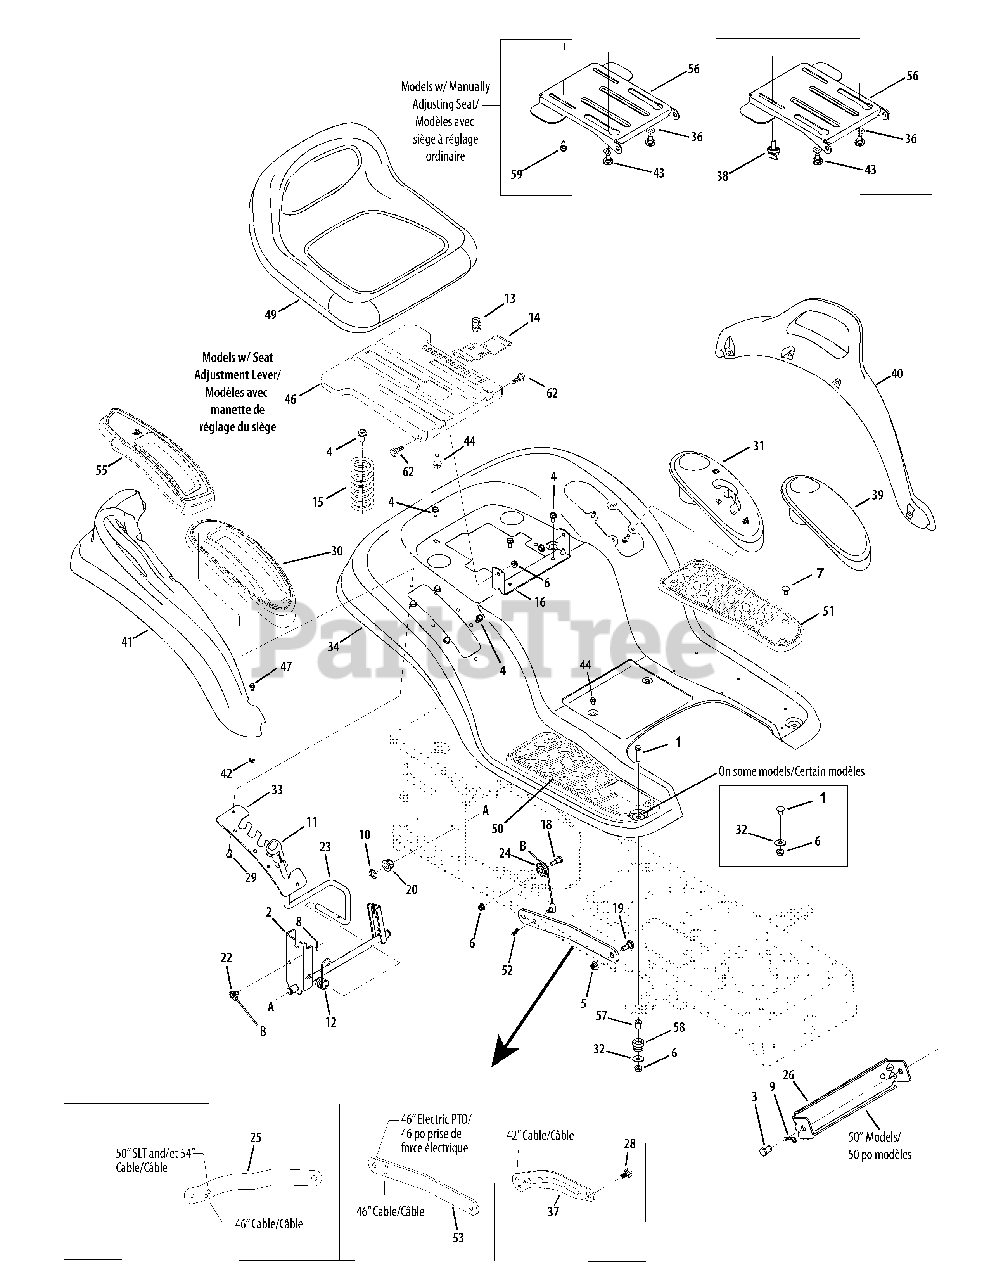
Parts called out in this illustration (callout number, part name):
1	Carriage Bolt 5/16 x 18 x .75" Lg.
2	Lift Shaft Assembly(42" and 46" Deck)
2	Lift Shaft Assembly (54" Deck)
4	S-Tapp Scr 5/16-18 x .75
5	Hex Flange Locknut 3/8-16 Gr. F,Ny lon
6	Hex Flange Locknut 5/16-18 Gr. F Ny lon
7	Clip-Ratchet
8	Int. Cotter Pin 5/16 Dia.
9	Internal Cotter Pin .080 x 1.5625
12	Torsion Spring
13	Compression Spring .68 x 1.065 x .055
14	Seat Adjustment Lever
15	Compression Spring 1.71 x 3.735 x .238
16	Seat Pivot Bracket
18	Shoulder Scr. .437 Dia x .47
19	Shoulder Screw .500 x .25 (46"/50")
20	Hex Flange Bearing .630 ID
22	Lift Cable, 16.16
24	Roller Pulley
25	Arm Lift (46" deck w/manual PTO & 50" deck)
25	Arm Lift (54" deck)
26	Deck Stabilizer Bracket
28	Shoulder Screw .625 x .175: 3/8-16
29	Hex Scr. 1/4-15 x .75
30	Lift Lever Cover
31	Shift Lever Cover w/Cup Holder
32	Flat Washer .344 ID x 1.0
33	Lift Adjustment Bracket
34	Fender 9 (Hydrostatic Models Only)
36	Flat Washer .406 x .875 x .059
37	Deck Lift Arm RH (42" Deck)
38	Knob, 3/8-16 x .625
39	Cover w/Cup Holder
40	LH Fender Flare
41	RH Fender Flare
42	Sems Hex Nut 1/4-20
43	Shoulder Spacer .625 x .175, 3/8-16
44	Hex Flg. Bolt 3/8-16 x.875
45	Shoulder Bolt .437 Dia. x .268
46	Seat Mounting Bracket
47	Carriage Bolt 1/4-20 x 1.00" Lg.
49	High Back Seat Black (w/arm rests)
52	Cotter Pin 3/32 dia. x 1.00 Lg.
53	Arm Lift (46"/54" deck w/Electric PTO)
55	Lift Lever Cover (Model 60R)
56	Seat Pivot Bracket, Manually Adjusted
58	Flg. Spacer .3125 x .4375 x .625
59	Hex Wash Hd Scr. 3/8-16 x .625 Gr. 5
